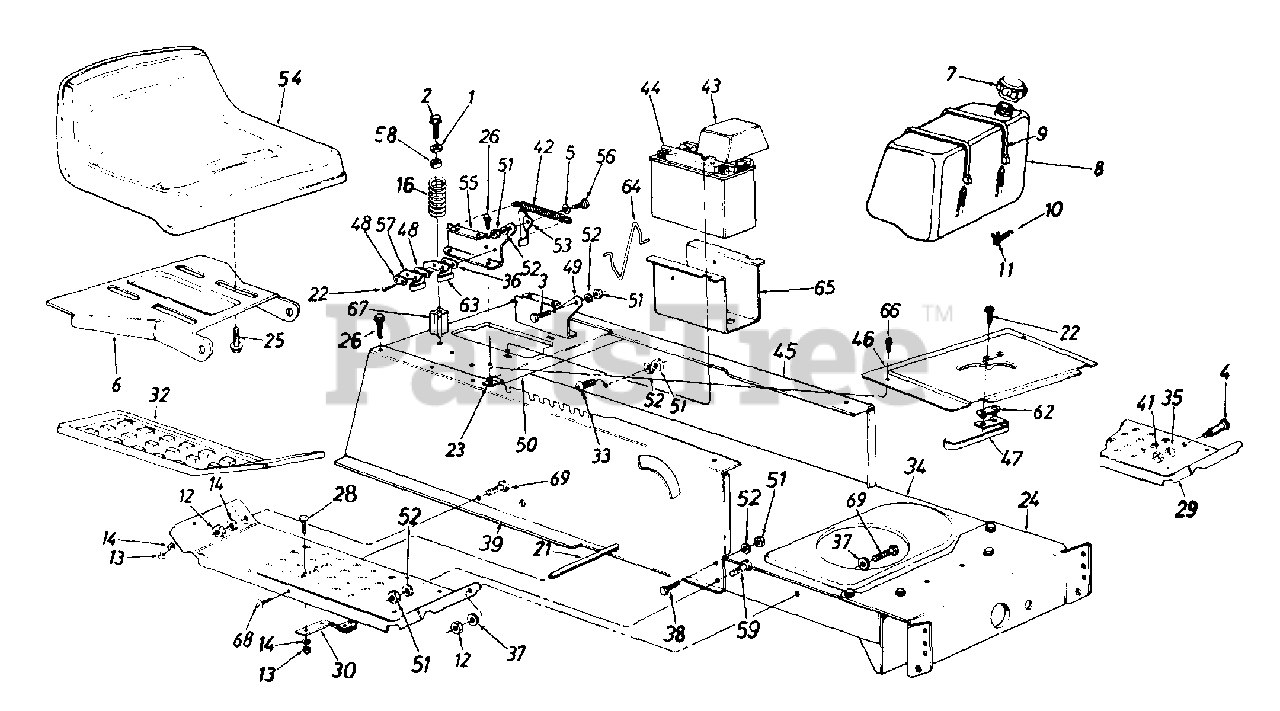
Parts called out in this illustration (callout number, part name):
1	Fl-Wash..344" I.D. x.875"
2	Hex Wash. Hd. Tap Scr. 5/16-18 x 3.25" Lg.
3	Shld. Bolt .437" Dia. x .162"
4	Shld. Bolt .50" Dia. x .84"
5	Spr-Wash..445" I.D. x .75
6	Seat Pivot Bracket
7	Fuel Cap
8	Fuel Tank
9	Tie Strap
10	Fuel Line
11	Hose Clamp
12	Hex Nut 1/4-28 Thd.
13	Hex Nut 1/4-20 Thd.
14	L-Wash. 1/4" I.D.
16	Compression Spring
21	Running Board Rod
22	Hex Wash. Hd. AB-Tap Scr. #8 x .50" Lg.
23	Speed Nut #102
24	Front Pivot Brkt.
25	Hex Tap Scr. 3/8-16 x .75"
26	Hex Wash. Hd. AB-Tap Scr. 5/16 x .75" Lg.
28	Carriage Bolt 1/4-20 x .62"
29	Running Board (R.H. & L.H.)
30	Blade Brake Ass'y.
32	Rubber Foot Pad - L.H.
33	Truss Mach. Scr. 5/16-18 x .75" Lg.
34	Lower Frame
35	L-Wash. 3/8" I.D.
36	Insulator Boss Plate
37	Fl-Wash..25" I.D. x .625" O.D.
38	Hex Bolt 5/16-18 x .75" Lg.
39	Upper Frame - R.H.
41	Hex Nut 3/8-16 Thd.
42	Extension Spring 5.31" Lg.
43	Battery Cover
44	12-V Battery
45	Upper Frame - L.H.
46	Shift Cover
47	Reverse Safety Switch
48	Insulator Plate
49	Seat Pivot Brkt. Support - L.H.
52	L-Wash. 5 16" I.D.
53	Seat Lift Brkt.
54	Seat 8-7/8" High
56	Shld. Bolt .437" Dia. x .268"
57	Spring Switch
58	Bushing
59	Hex Wash. TT-Tap Scr. 5/16-18 x 7/8" Lg.
62	Insulator Nut Plate
63	Safety Switch (Seat)
64	Battery Tray Clip
65	Battery Tray
66	Truss Mach. B-Tap Scr. #10 x .5" Lg.
67	Spring Spacer
68	Pan Hd. Cutting Scr. 5/16-18 x .75" Lg.
69	Hex Bolt 1/4-28 x .75" Lg.
